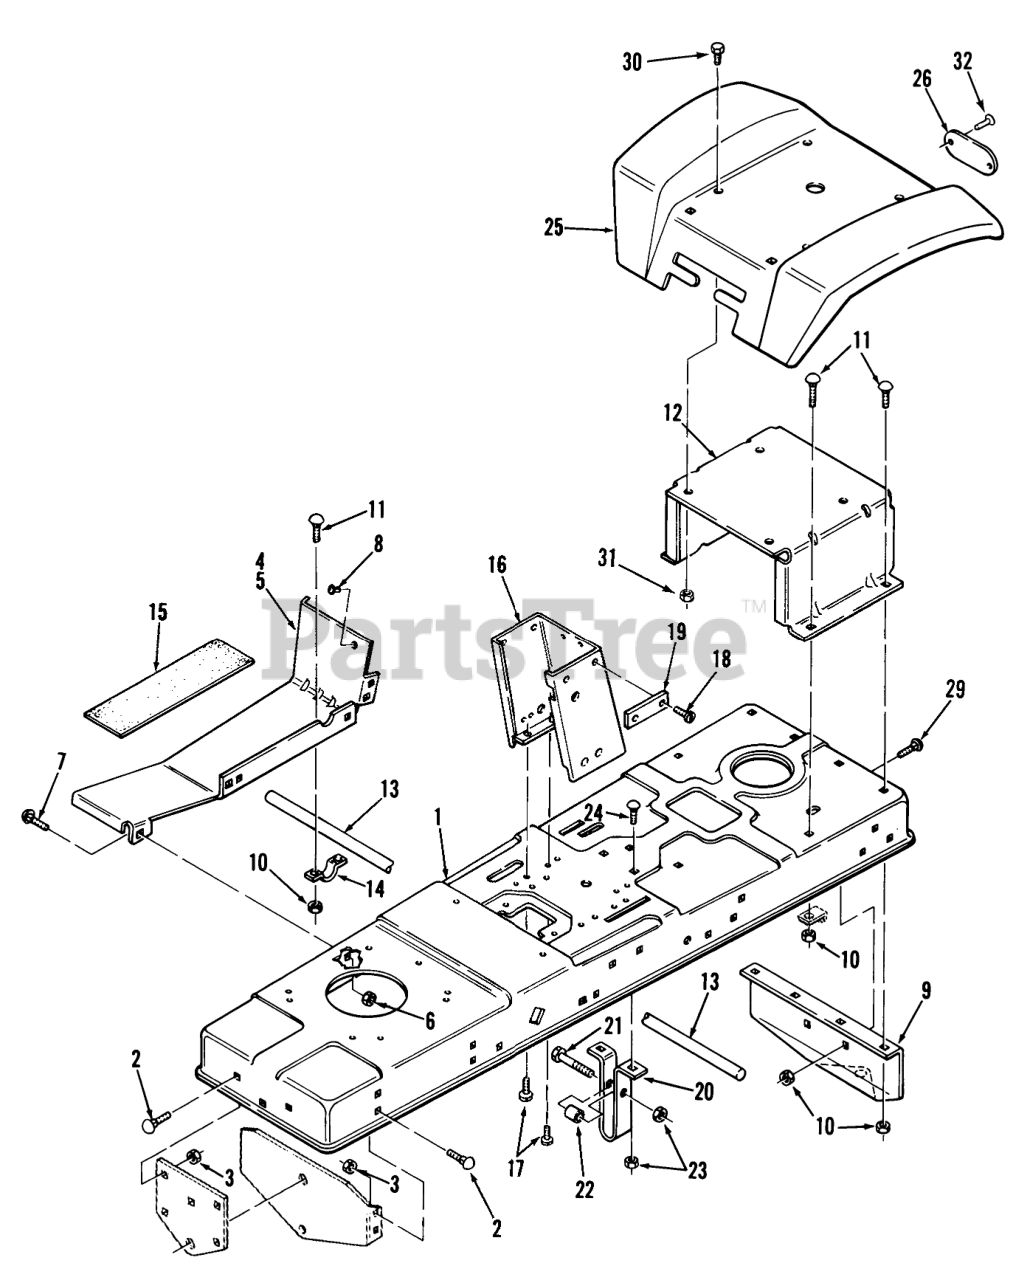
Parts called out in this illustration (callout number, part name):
1	Frame
2	CARRIAGE BOLT -4
3	Nut
4	Footrest RH
6	Nut
7	CARRIAGE BOLT -4
8	BUMPER-RUBBER
9	Hitch-Drawar
10	Nut
11	CARRIAGE BOLT -4
12	SUPPORT-SEAT R
13	SHAFT-REAR
14	CLAMP
15	PAD-FOOTREST
16	ASSY-HOODSTAND
17	SCREW
18	HEX WASH HD SCREW
19	Spacer
20	GUIDE-MOWER
21	Bolt
22	SPACER
23	Nut
24	Bolt-Carriage
25	Assy-Fender & Plate
26	Reflector
29	Bolt
30	H H C S
31	Nut
32	Poprivet
